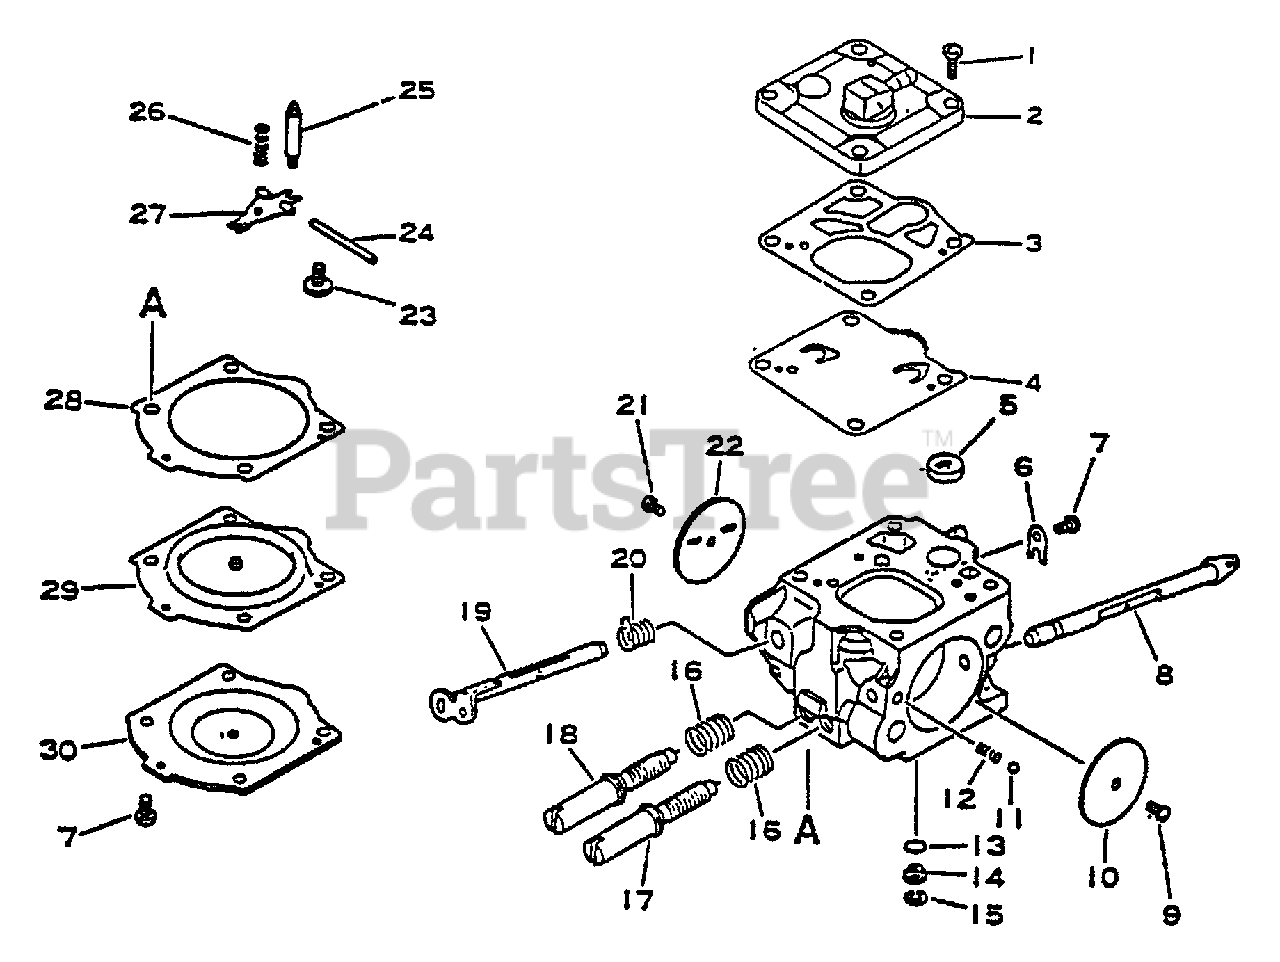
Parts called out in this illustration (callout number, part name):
1	SCREW, PUMP COVER
2	COVER, PUMP
3	GASKET, PUMP
4	DIAPHRAGM, PUMP
5	STRAINER
6	RING, RETAINING
7	SCREW
8	SHAFT, CHOKE
10	VALVE, CHOKE
11	BALL, CHOKE
12	SPRING
13	O-RING
14	JET - 42
15	WASHER
16	SPRING
17	NEEDLE - HIGH SPEED
18	NEEDLE - LOW SPEED
19	SHAFT, THROTTLE
20	SPRING, THROTTLE RETURN
21	SCREW
22	VALVE, THROTTLE
23	SCREW, METERING LEVER PIN
24	PIN, METERING LEVER
25	VALVE, INLET NEEDLE
26	SPRING, METERING LEVER
27	LEVER, METERING
28	GASKET, METERING
29	DIAPHRAGM, METERING
30	COVER, METERING
30	REPAIR KIT
30	DIAPHRAGM/GASKET KIT
